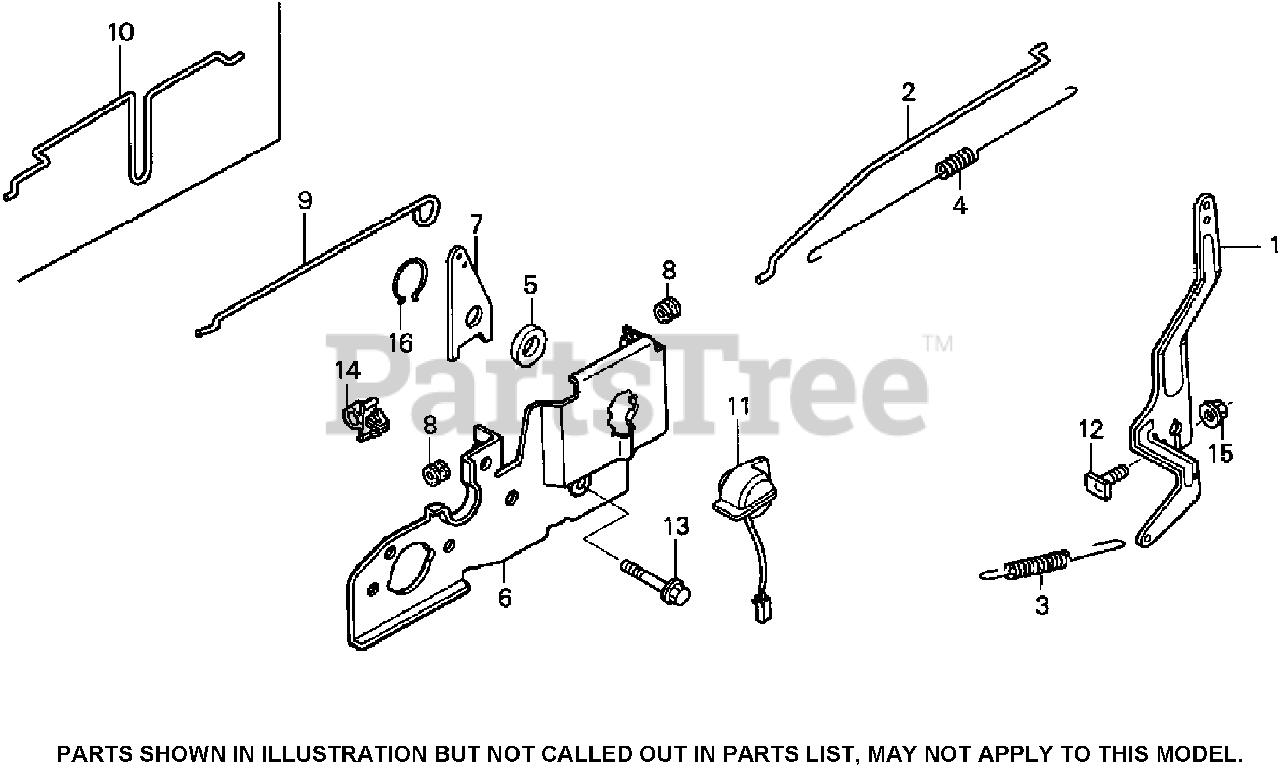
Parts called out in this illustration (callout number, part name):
1	ARM-GOVERNOR
2	ROD-GOVERNOR
3	SPRING-GOVERNOR
4	SPRING-RETURN, THROTTLE
6	BASE-CONTROL
12	BOLT-ARM, GOVERNOR
13	BOLT-FLANGE (6X45)
15	NUT-FLANGE (6MM)
